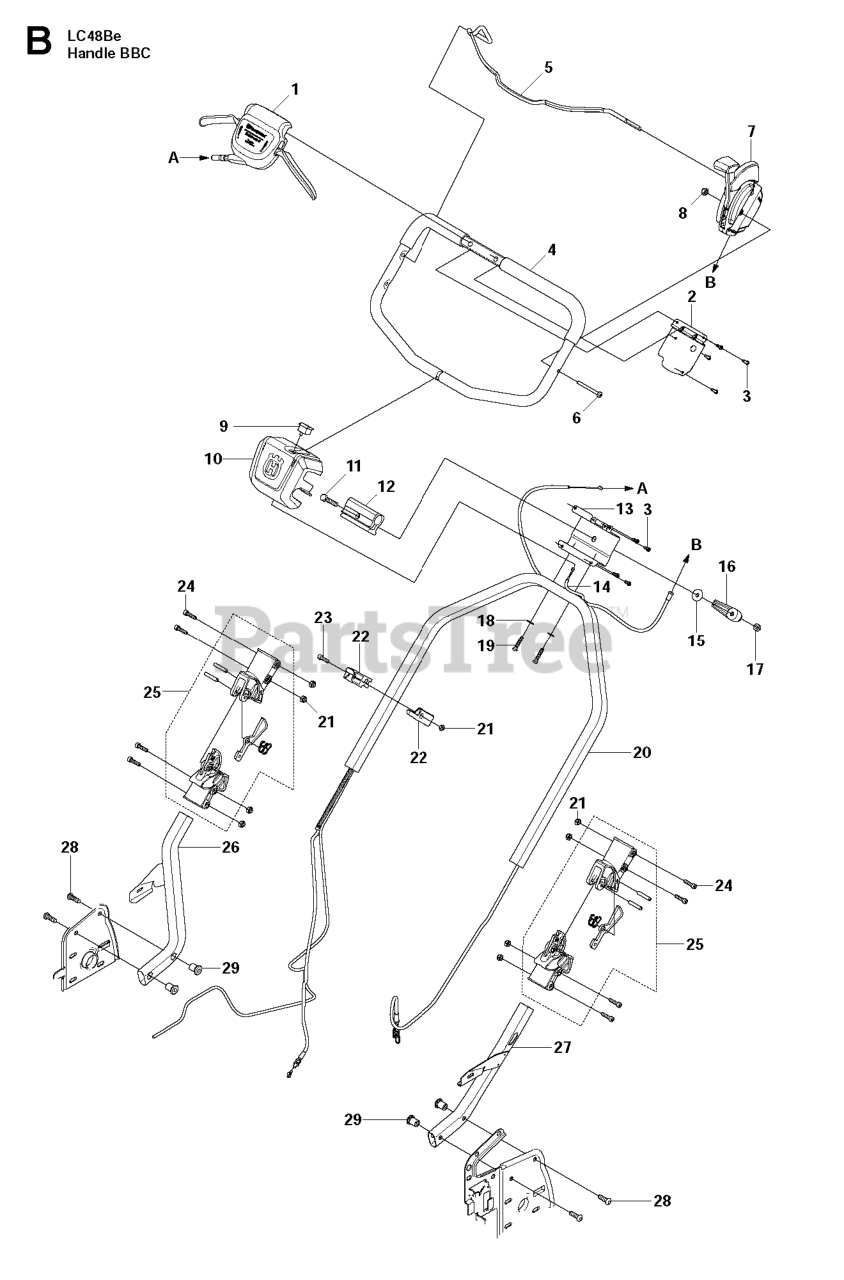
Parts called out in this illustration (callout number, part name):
15	WASHER - 25X8.5X2.3
23	SCREW MC6S 6X20
24	REPL BY 725 53 74-55
